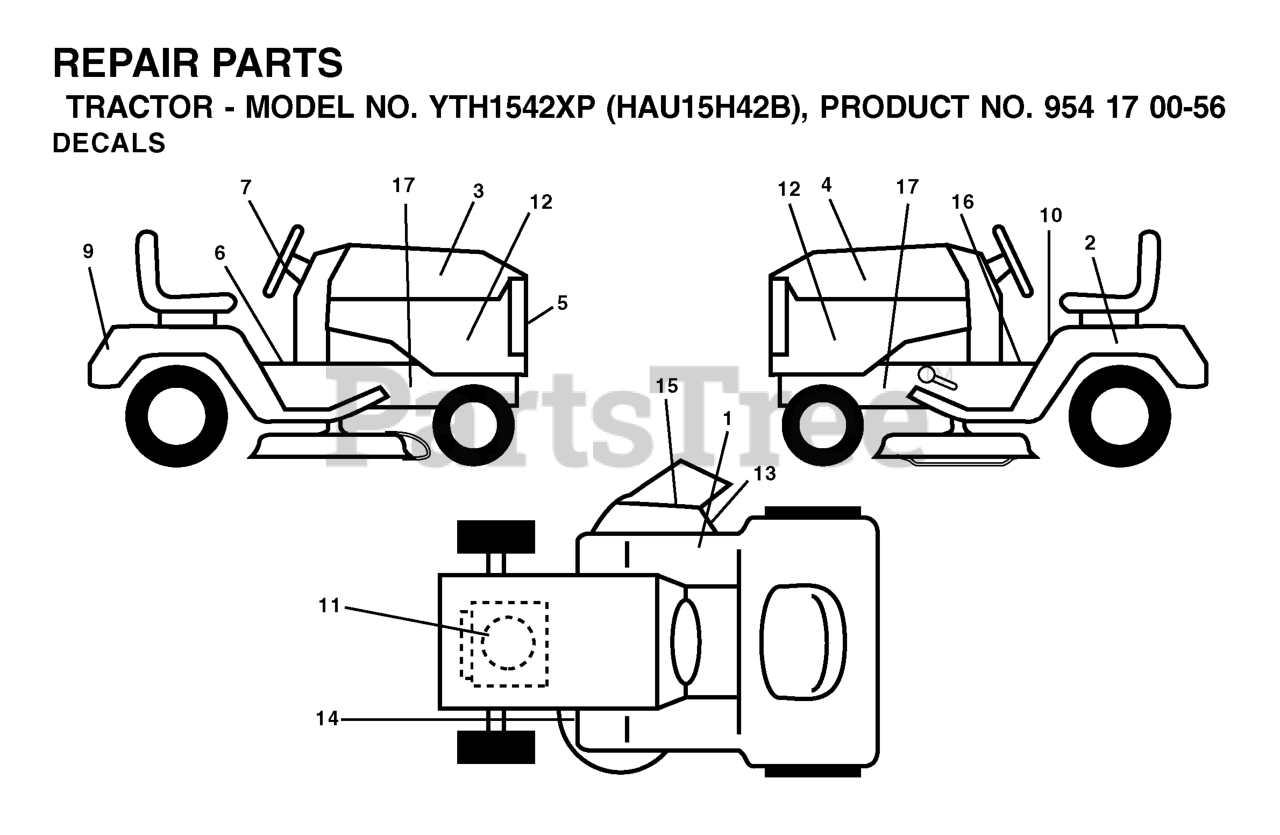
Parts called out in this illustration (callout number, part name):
1	DECAL
2	DECAL BTRY SYMBOLS
3	DECAL HOOD RH
4	DECAL HOOD(L)YTH1542XP
5	DECAL.GRILLE.HUSQ
6	DECAL PARK BRAKE
7	DECAL.WHEEL.STEERING.HUSQ.PERM
9	DECAL, FENDER
10	DECAL READ OWNER'S MAN SYMS
12	DECAL HOOD
13	DECAL.INTERNATIONL.CUTFINGER
14	DECAL V BELT SCHEMATIC
15	DECAL DECK "B" 42"
16	DECAL
